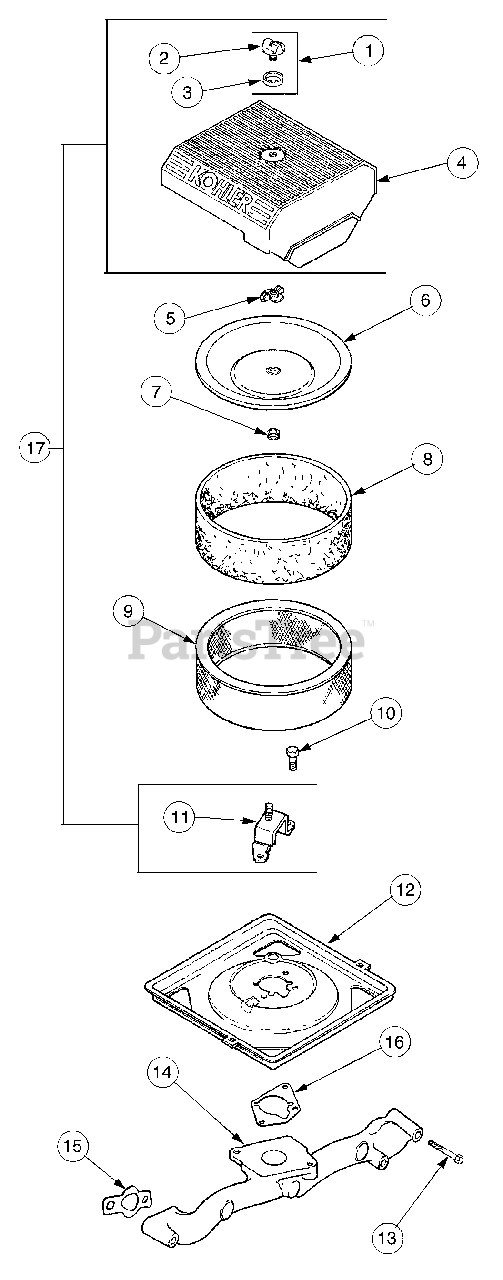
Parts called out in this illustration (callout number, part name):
1	Kit, Knob w/Seal
3	Seal, Air Cleaner Cover Knob
4	Cover, Air Cleaner
6	Cover, Inner Air Cleaner
7	Seal, Inner Air Cleaner
8	Precleaner, Element
9	Element, Air Cleaner
10	Screw, Hex Flange, M6 x 1.0 x 16
11	Bracket, Air Cleaner Base
12	Base, Air Cleaner
13	Screw, Hex Flange, M6 x 1.0 x 55
14	Manifold, Intake
15	Gasket, Intake Manifold
16	Gasket, Air Cleaner Base
17	Kit, Air Cleaner Cover
